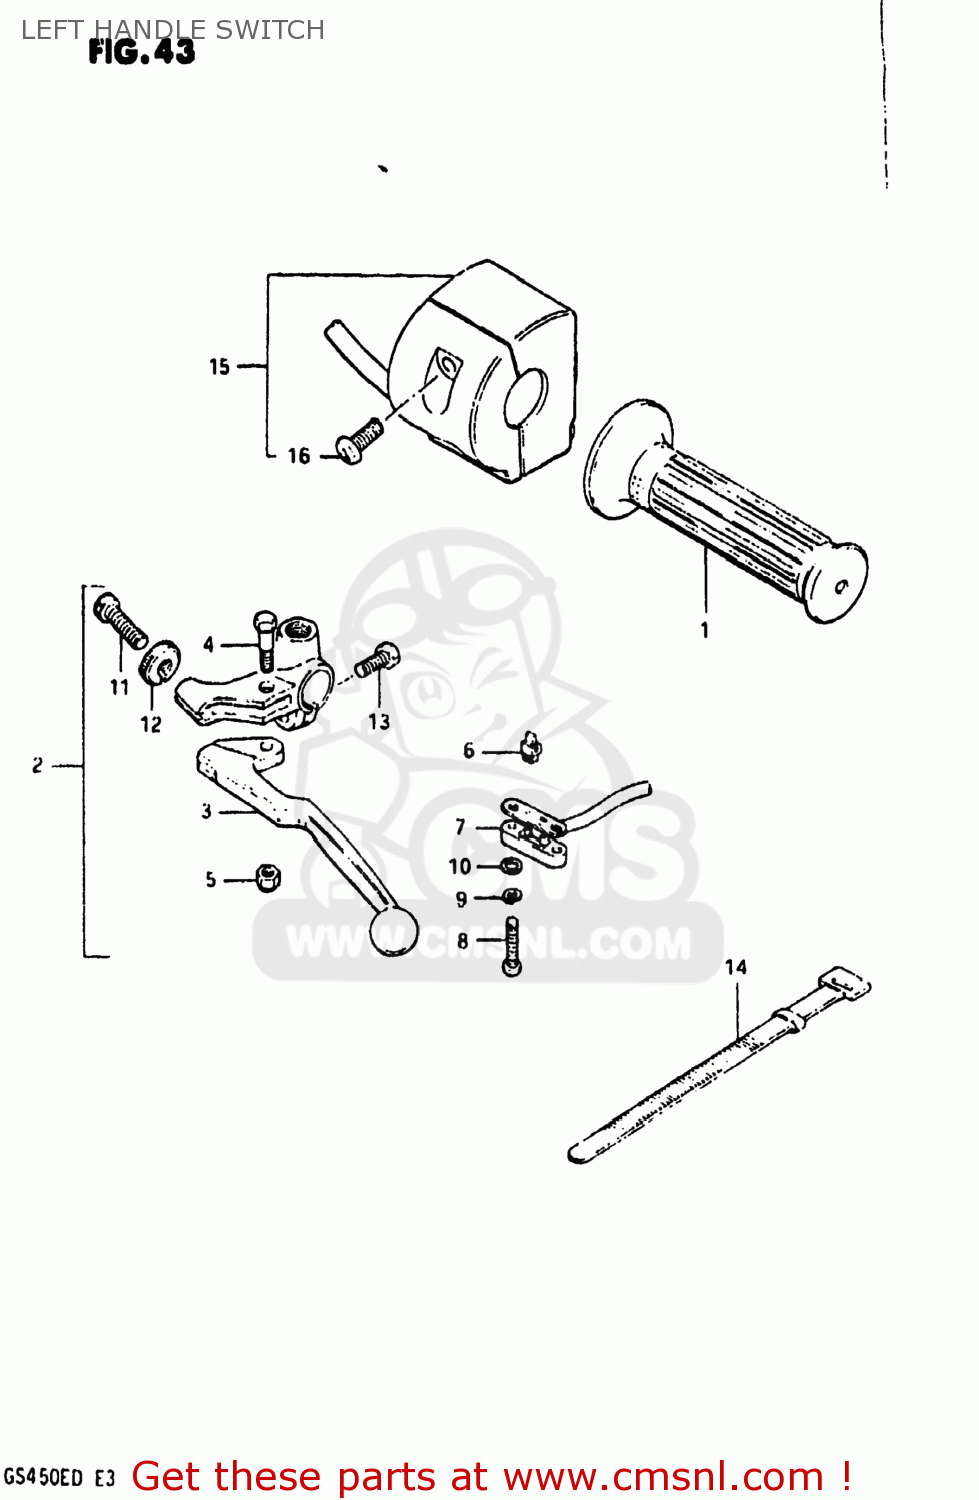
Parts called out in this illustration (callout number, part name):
1	GRIP,LEFT
2	LEVER ASSEMBLY
3	LEVER,CLUTCH
4	BOLT,LEVER
5	NUT 6MM
6	CONTACT,SWITCH
7	COVER,FR BK TERMINAL BASE
8	SCREW
9	LOCK WASHER
10	WASHER
11	ADJUSTER,CABLE
12	NUT,CABLE ADJUSTER LOCK
13	BOLT,CLUTCH LEVER HOLDER
14	CLAMP(L:120)
15	SWITCH ASSEMBLY,HANDLE,LEFT
16	SCREW
